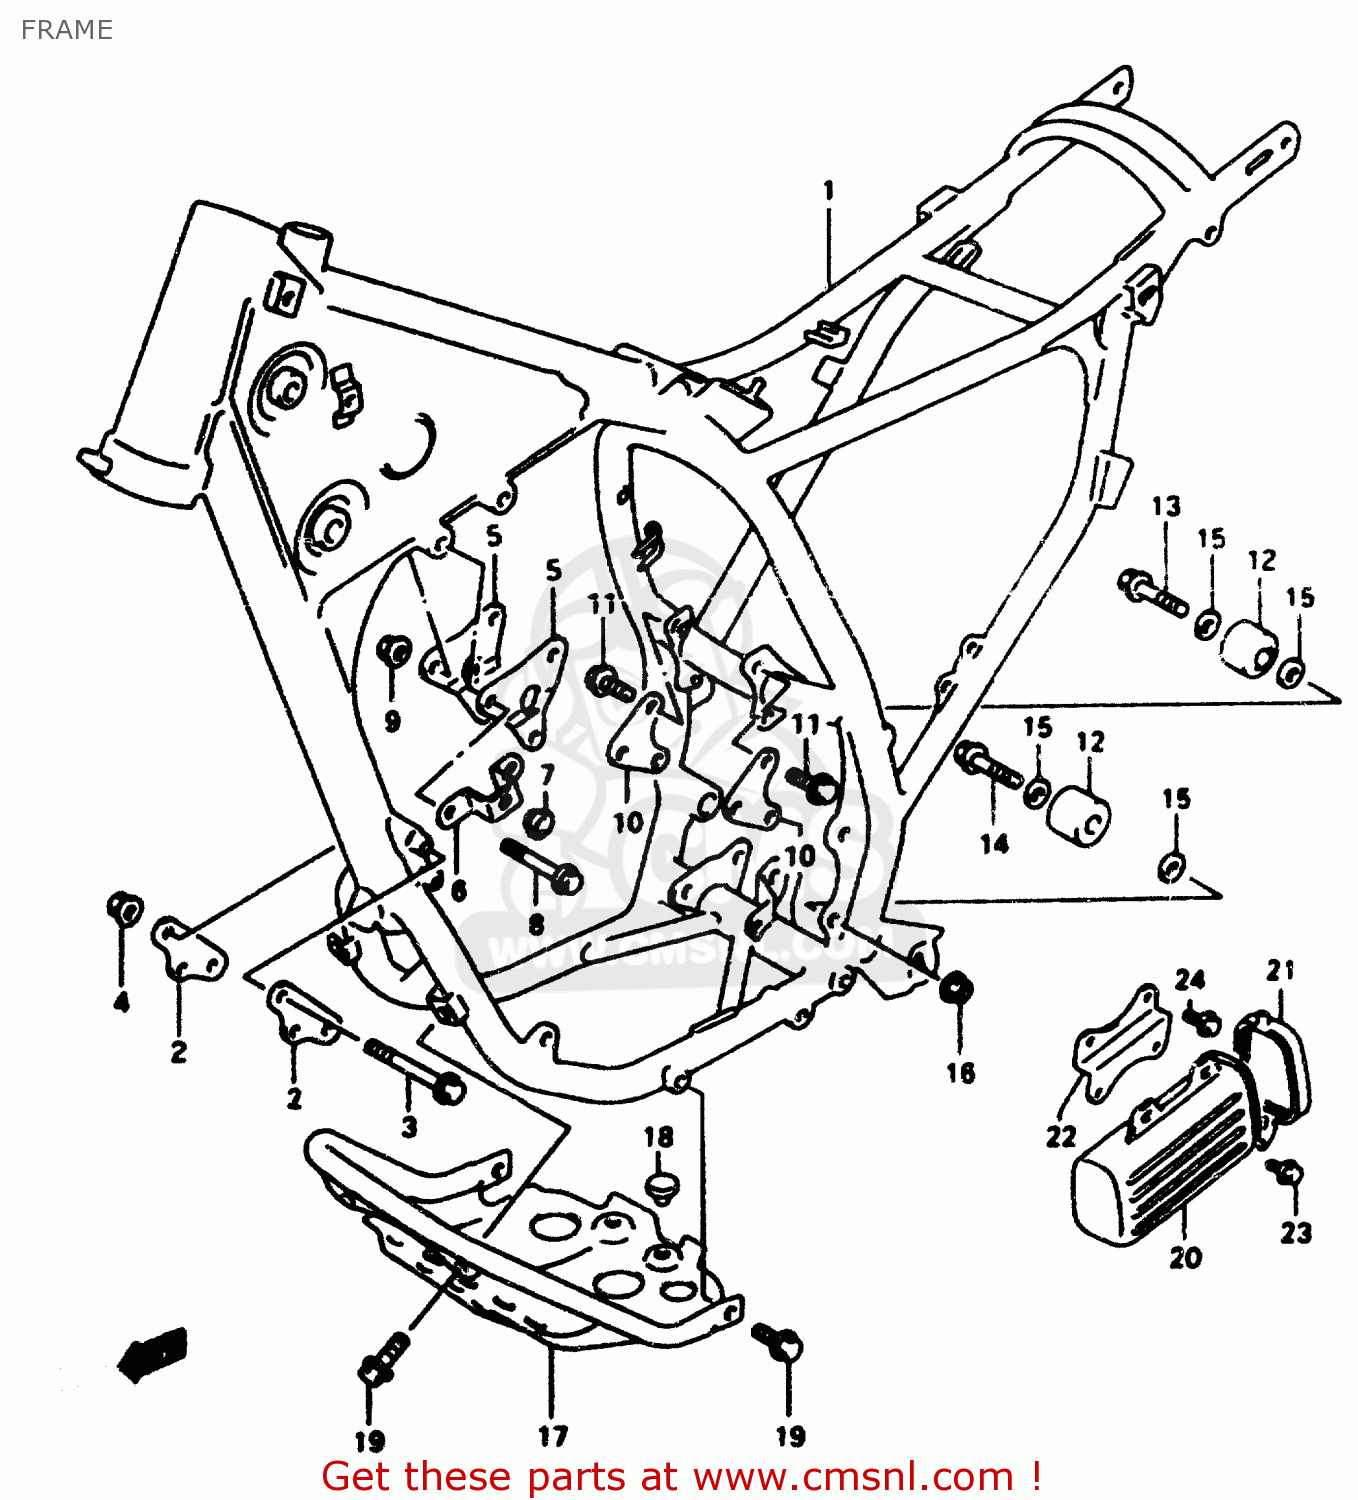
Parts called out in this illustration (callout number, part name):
1	FRAME COMP
2	PLATE,ENGINE MOUNT FR
3	BOLT(8X85)
4	NUT
5	PLATE,ENGINE MOUNT UPR
6	PLATE,FUEL TANK STOPPER
7	CUSHION
8	BOLT(8X70)
9	NUT
10	PLATE,ENGINE MOUNTING,REAR
11	BOLT(8X16)
12	ROLLER,CHAIN
13	BOLT(8X38)
14	BOLT 8X45
15	SHIM(8X12X1)
16	NUT
17	PROTECTOR,ENGINE(SILVER)
18	CUSHION
19	BOLT
20	GRIP,RR
21	HOLDER,TOOL
22	CAP,TOOL HOLDER
23	PLATE,TOOL HOLDER FITING
24	BOLT 6X16
25	BOLT
26	CARRIER,SPORT
27	LABEL,WARNING
